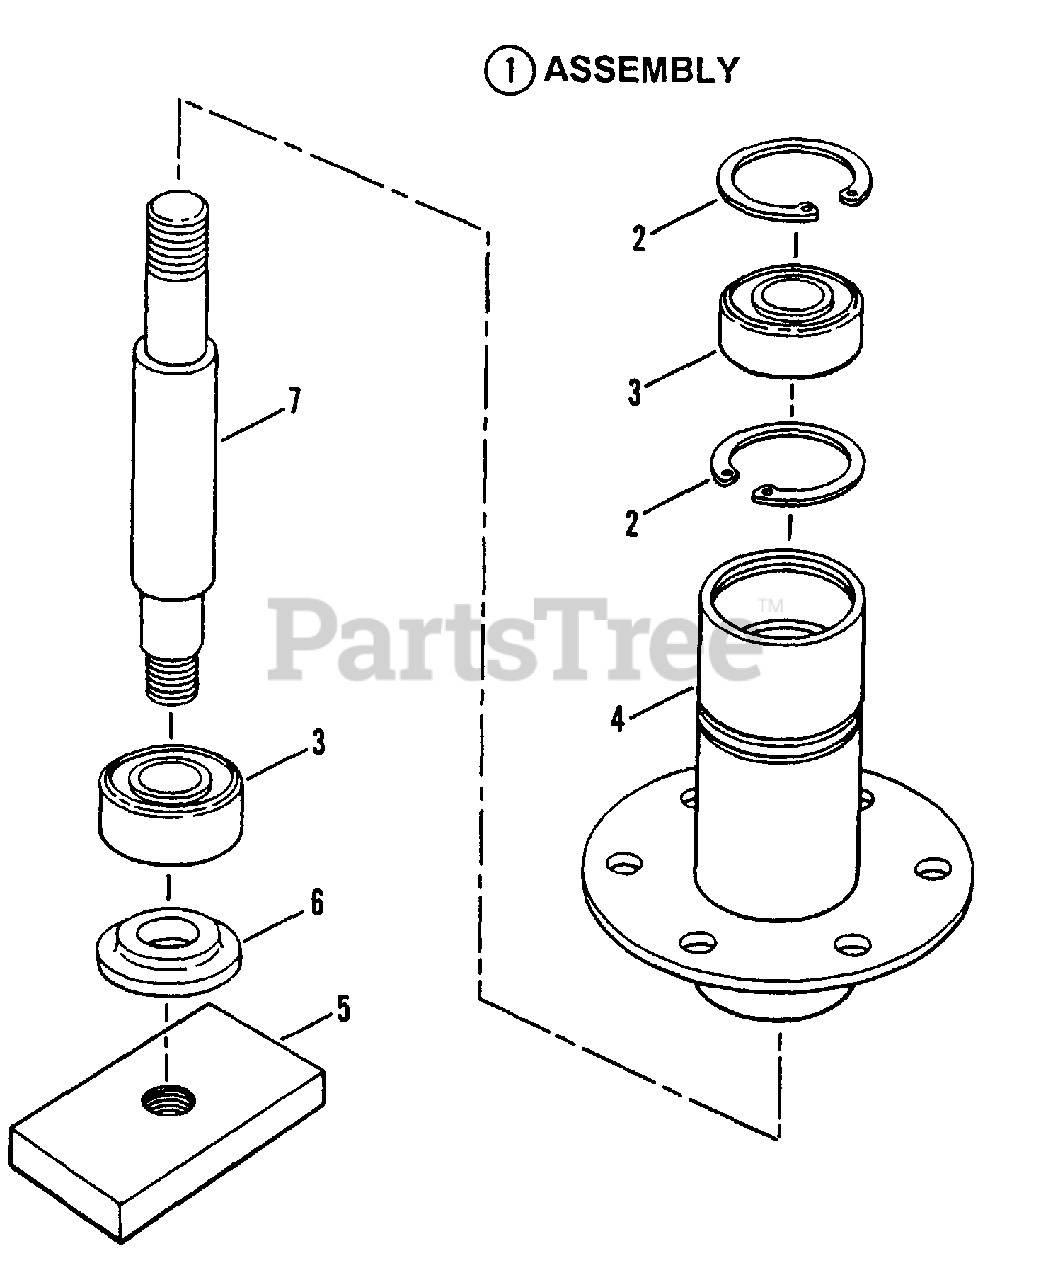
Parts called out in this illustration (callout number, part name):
1	ASSEMBLY, Spindle Housing, 42" Cutting Deck
2	RING, Retaining
3	BEARING, Spindle
4	HOUSING, Spindle
5	HOLDER, Blade
6	WASHER, Spindle
7	SPINDLE 6.5" Long
